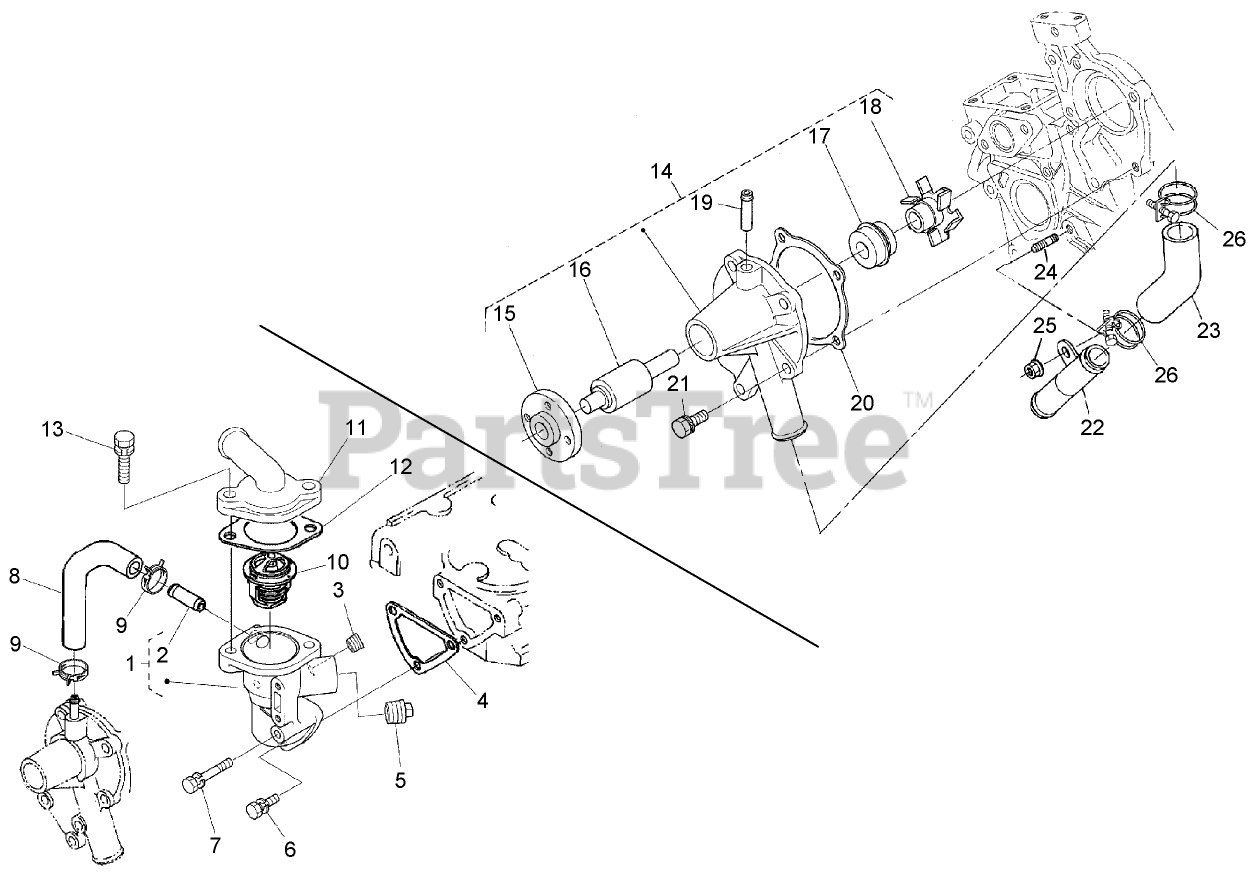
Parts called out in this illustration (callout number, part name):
1	WATER FLANGE ASM
2	PIPE-RETURN, WATER
4	GASKET-FLANGE, WATER
7	BOLT
8	PIPE-RETURN, WATER
9	BAND-PIPE
10	THERMOSTAT ASM
11	COVER-THERMOSTAT
12	GASKET
14	WATER PUMP ASM
15	FLANGE-PUMP, WATER
16	BEARING-BALL
17	WATER PUMP SEAL ASM
18	IMPELLER-PUMP, WATER
19	PIPE-RETURN, WATER
20	GASKET-PUMP, WATER
22	PIPE-WATER
23	PIPE-WATER
25	NUT-FLANGE
26	BAND-PIPE
